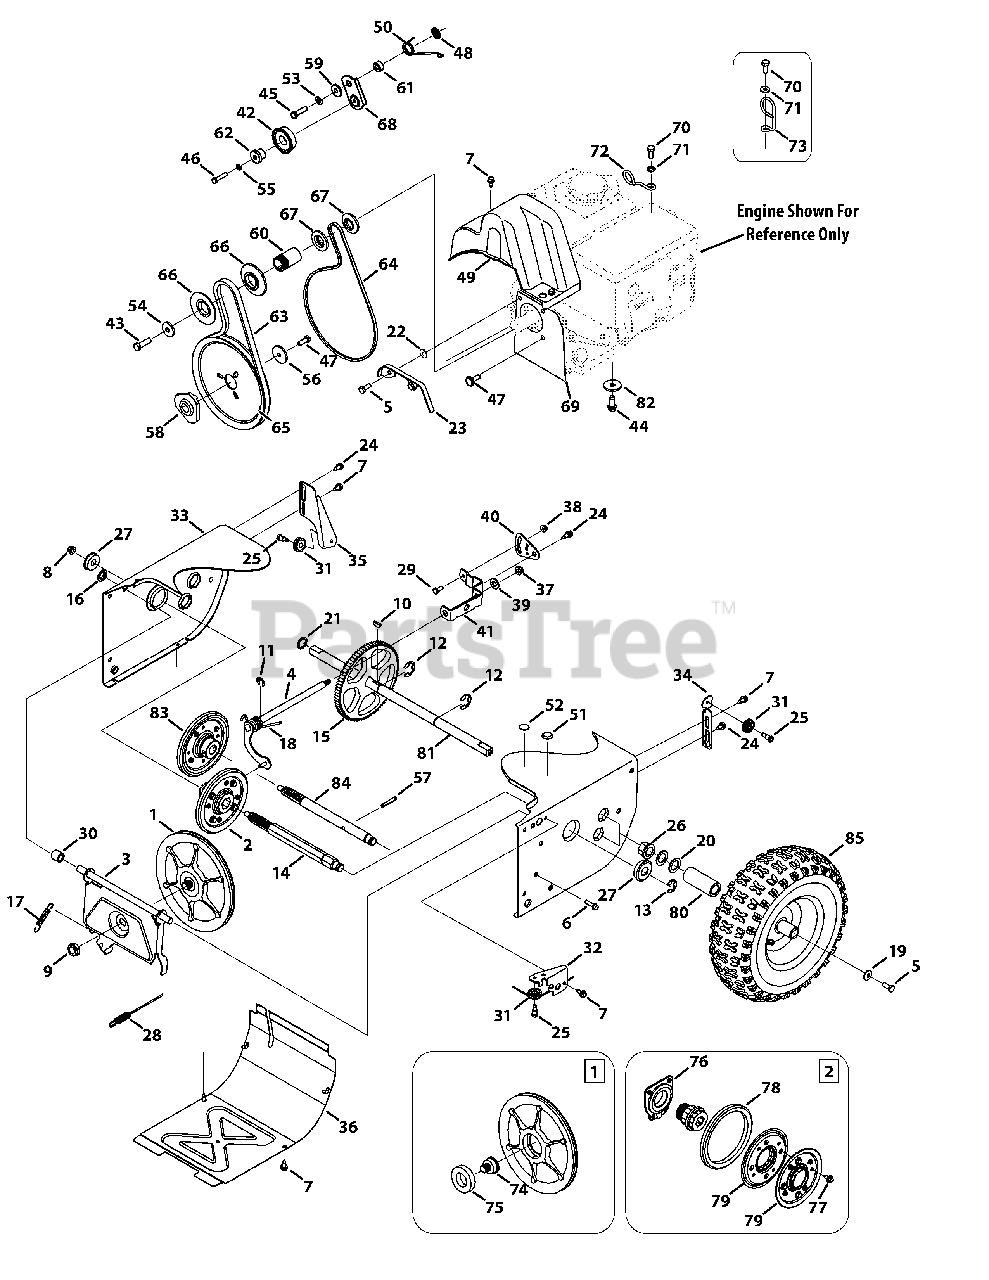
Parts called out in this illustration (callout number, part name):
1	Disc Assembly, Friction Wheel
2	Friction Wheel Assembly, 5.5 OD
3	Friction Wheel Support Bracket
4	Rod Shift Assembly
5	Hex Head Screw, 5/16-24 x .750
6	Taptite Screw, 1/4-20 x 1.000
7	Taptite Screw, 1/4-20 x .625
8	Flange Lock Nut, 3/8-16
9	Flange Nut, 5/8-18
10	Hi-pro Key, 3/16 x 3/4 Dia.
11	E-Ring
12	Retaining E-Ring, .875 Dia.
13	E-Ring, .750 Dia.
14	Hex Shaft, 7-Tooth
15	Gear, 80-Tooth
16	Speed Nut, .500
17	Extension Spring
18	Torsion Spring, .750 x .968
19	Bell Washer, .340 x .872 x .060
20	Flat Washer, .793 x 1.24 x .060
21	Flat Washer, .75 x 1.00 x .060
22	Washer, Flat, .385 x .62 x .063
23	Belt Cover
24	Shoulder Screw, .368 x .113, 1/4-20
25	Shoulder Screw, 1/4-28, .340 x .355
26	Hex Flange Bearing
27	Ball Bearing, 17 x 40 x 12
28	Wheel Clutch Cable, 44.95"
29	Hex Head Screw, 1/4-20 x .620
30	Spacer, .508 ID x .75 OD x .68
31	Cable Roller
32	Auger Cable Front Guide Bracket
34	Auger Cable Guide Bracket
35	Drive Cable Guide Bracket
36	Frame Cover - Red
36	Frame Cover - Black
36	Frame Cover - Green
37	Flange Lock Nut, 5/16-18
38	Flange Lock Nut, 1/4-20
39	Washer, Flat, .469 x .875 x .105
40	Speed Selector Pivot Bracket
41	Speed Selector Shift Bracket
42	Idler Pulley Assembly
43	Hex Screw, 3/8-24 x 1.25
44	Sems Screw, 3/8-16 x 1.00
45	Hex Screw, 5/16-24 x 1.25
46	Hex Screw, 1/4-20 x 1.25
47	Shoulder Screw, 5/16-24 x .5
48	Push-on Nut, .25 Dia.
49	Belt Cover, 4-Way large block
49	Belt Cover, 4-Way
49	Belt Cover, Standard
50	Torsion Spring, .850 ID x .333
51	Plug, 3/8 ID
52	Plug, 1/2 ID
53	Lock Washer, 5/16
54	Flat Washer, .406 x 1.25 x .157
55	Washer, Lock, 1/4
56	Flat Washer, .34 x 1.50 x .150
57	Pin, Spirol, 2.5"
58	Adapter Pulley, .75 Dia.
59	Shoulder Spacer, .3175 x .5 x .0975
60	Spacer, .875 ID x 1.185 OD
61	Spacer, .340 x .750 x .330
62	Shoulder Space, .260 x .785 x .538
63	Auger Drive Belt, 4-Way large Block
63	Auger Drive Belt, Standard
64	Wheel Drive Belt, 4-Way large block
64	Wheel Drive Belt, Standard
65	Auger Drive Pulley, 8.1 x .5
66	Pulley Half, 2.600 OD
67	Pulley Half, 3/8 x 1.716 OD
68	Wheel Drive Idler Bracket
69	Cover Plate, 4-Way large block
69	Cover Plate, Standard
70	Hex Head Screw, 1.25 x 20
71	Washer, Flat, .330 x .630 x .0635
72	Cable Guide
73	Cable Guide
74	Friction Disc Bearing Pin
75	Ball Bearing, 30 x 55 x 13
76	Bearing Assembly
77	Screw, 1/4-14 x .625
78	Friction Wheel Rubber
79	Friction Wheel Plate
80	Spacer, 1.25 x .75 x 3.0
80	Spacer, 1.25 x .75 x 1.50
81	Axle, .75 x 20"
81	Axle, .75 x 22"
82	Washer, Flat, .38 x 1.38 x .125
83	Friction Wheel Ass’y, Single-Speed
84	Shaft, Single-Speed
85	Snow Hog Wheel, 13 x 4 x 6
85	Snow Hog Wheel, 15 x 5 x 6
85	Snow Hog Wheel, 15 x 4.8
